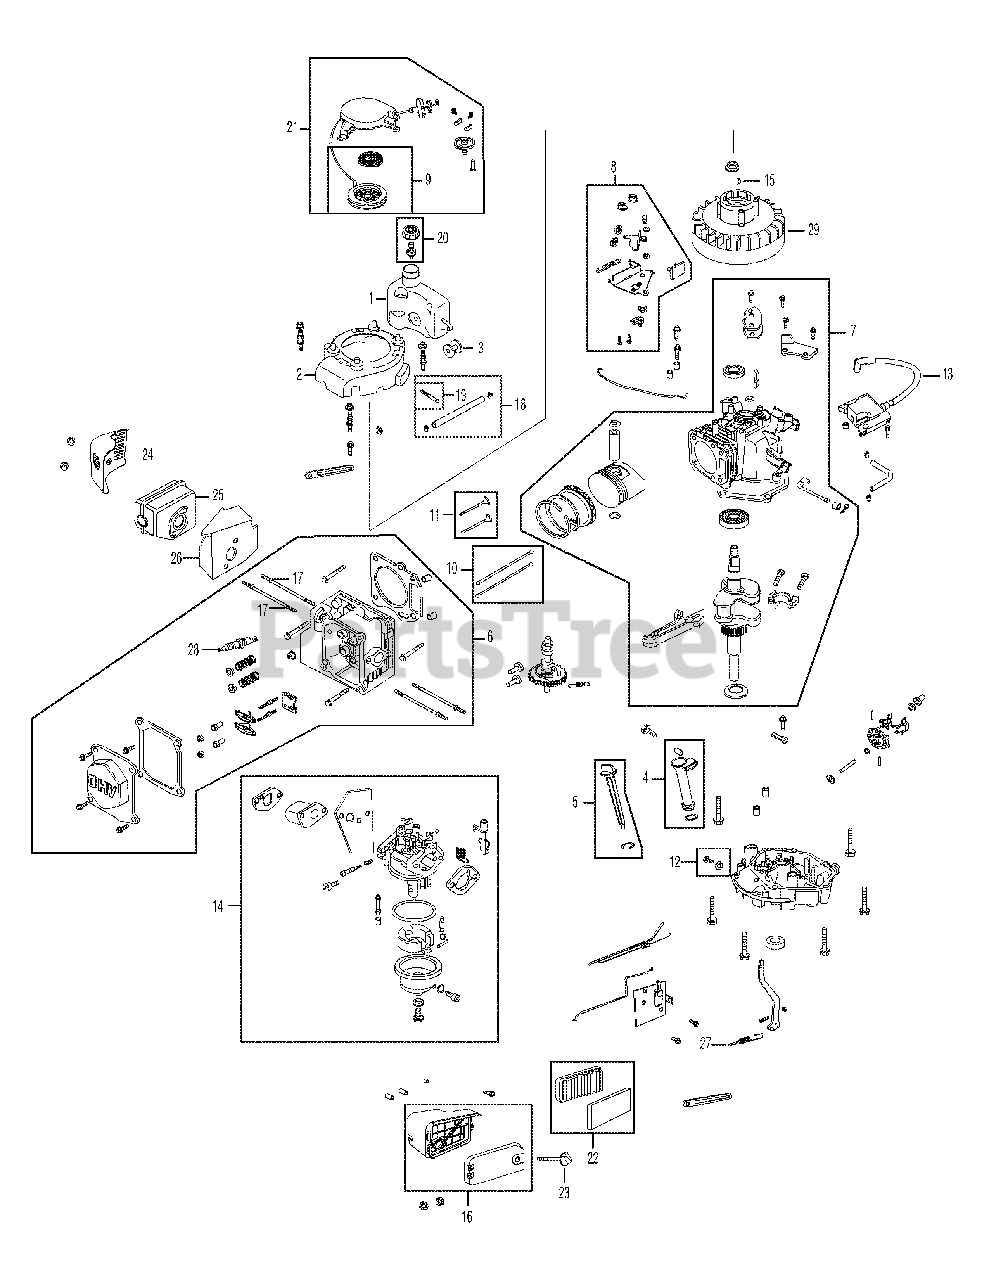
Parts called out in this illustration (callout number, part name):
1	Fuel Tank
2	Flywheel Shroud
3	Rubber Fuel Tank Mounting Washer
4	Oil Filler Tube Assembly
5	Dipstick Assembly
6	Cylinder Head Complete
7	Short Block Assembly
8	Stop Switch and Brake Assembly
9	Recoil Spring and Pulley Assembly
10	Push Rod Kit
11	Valve Kit
12	Oil Drain Plug and Washer Assembly
13	Ignition Coil
14	Carburetor Assembly
15	Flywheel Key
16	Air Cleaner Housing Assembly Complete
17	Muffler Stud Assembly
18	Fuel Line Kit - Inc. hoses, clamps & filter
19	Fuel Filter
20	Fuel Cap Assembly
21	Recoil Starter Assembly
22	Air Cleaner Kit
23	Air Cleaner Thumb Screw
24	Muffler Guard
25	Muffler
26	Muffler Gasket /Heat Shield
27	Governor Return Spring
28	Spark Plug
29	Flywheel
